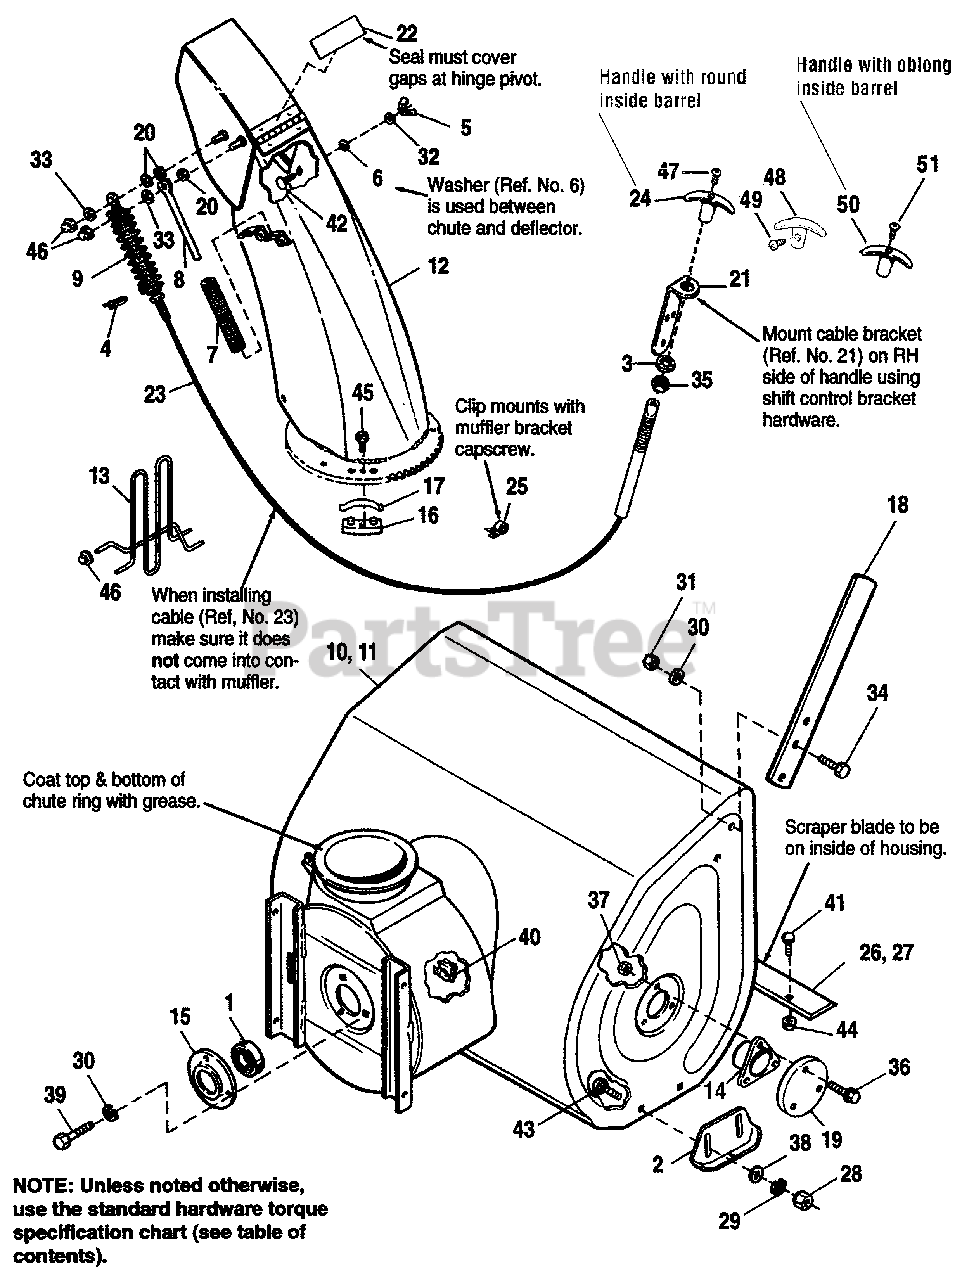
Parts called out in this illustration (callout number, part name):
1	BEARING, Ball
3	LOCKWASHER, Int. Tooth
4	TIE, Self-Locking Cable Assy.
5	NUT, ESNA 5/16-18
6	WASHER, Nylon
8	ROD, Spring
9	BOOT, Water
10	HOUSING ASSY., Auger, 8-70, 9-70
11	HOUSING ASSY., Auger, 10-80
12	CHUTE ASSY.
13	GUARD, Chute
14	BEARING, Auger
15	RETAINER, Bearing
16	HOLD DOWN, Chute
18	CUTTER, Drift (Available under P/N 1685189, see page 28)
19	BEARING, Cap
21	BRACKET, Cable
22	SEAL, Hinge
23	CABLE ASSY. (Incl. Ref. Nos. 3, 9, 21 & 36)
24	HANDLE, Cable
26	BLADE, Scraper, 8-70, 9-70
27	BLADE, Scraper, 10-80
28	NUT, Hex, 3/8-16
29	LOCKWASHER, 3/8
30	LOCKWASHER, 5/16
31	NUT, 5/16-18
32	WASHER, Flat, 11/32
33	WASHER, Flat
34	CAPSCREW, Hex Hd., 5/16-18 x 3/4
35	NUT, 5/16-18,
36	CAPSCREW, Hex Flange Whizlock 5/16-18 x 7/8
37	NUT, Hex, Center Lock, 5/16-18
38	WASHER, Flat, 13/32
39	CAPSCREW, Hex Hd., 5/16-18 x 17/64
40	NUT, Retainer, 5/16-18
41	CARRIAGE BOLT, Round Head Square Neck 5/16-18 x 5/8 (Qty. 7 on 10-80)
42	CARRIAGE BOLT, 5/16-18 x 3/4
43	CARRIAGE BOLT, 3/8-16 x 3/4
44	LOCKNUT, Flange, 5/16-18 (Qty. 7 on 10-80)
45	SCREW, Plastite #10
46	PUSH NUT
47	SCREW, Pan Hd., #8-32 x 11/16
49	SCREW, Set, Hex #10-24 x 3/8
50	KNOB
51	SCREW, 8-32
